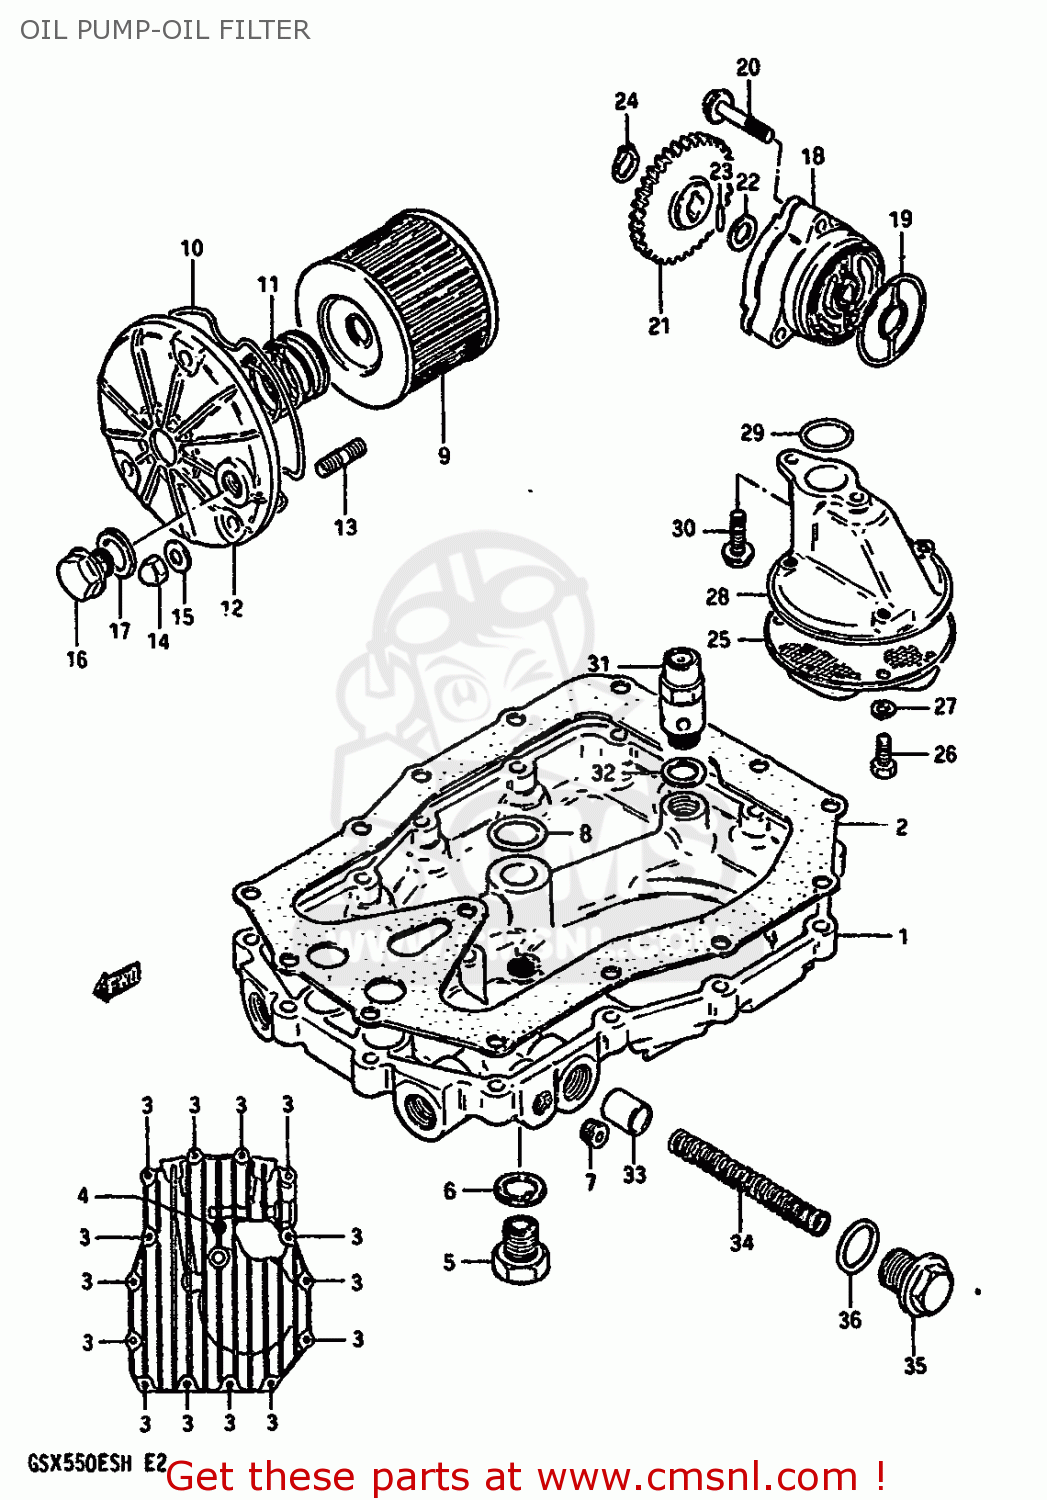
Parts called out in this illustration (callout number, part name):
1	PAN,OIL
2	GASKET,OIL PAN (MCA)
3	BOLT
4	BOLT 6X35
5	PLUG
6	GASKET(14X19.2X2) (NAS)
7	PLUG
8	O RING(D:3.2,ID:17.8)
9	FILTER ASSY,ENGINE OIL
10	O RING,OIL FILTER CHAMBER CAP
11	SPRING
12	CAP,OIL FILTER
13	STUD 6X20
14	NUT 6MM
15	WASHER
16	PLUG(14X12)
17	GASKET(14X19.2X2) (NAS)
18	PUMP ASSEMBLY,ENGINE OIL
19	O RING,OIL PUMP
20	BOLT(6X32)
21	GEAR,OIL PUMP DRIVEN
22	SHIM
23	PIN(4X15.8)
24	CIRCLIP
25	STRAINER,ENGINE OIL
26	BOLT
27	WASHER,LOCK
28	PROTECTOR,OIL STRAINER
29	O RING(D:3.2,ID:17.8)
30	BOLT,REAR
31	REGULATOR ASSEMBLY,ENGINE
32	WASHER
33	PLUNGER,OIL CONTROLL
34	SPRING
35	PLUG
36	O RING(D:2.4,ID:16.8)
